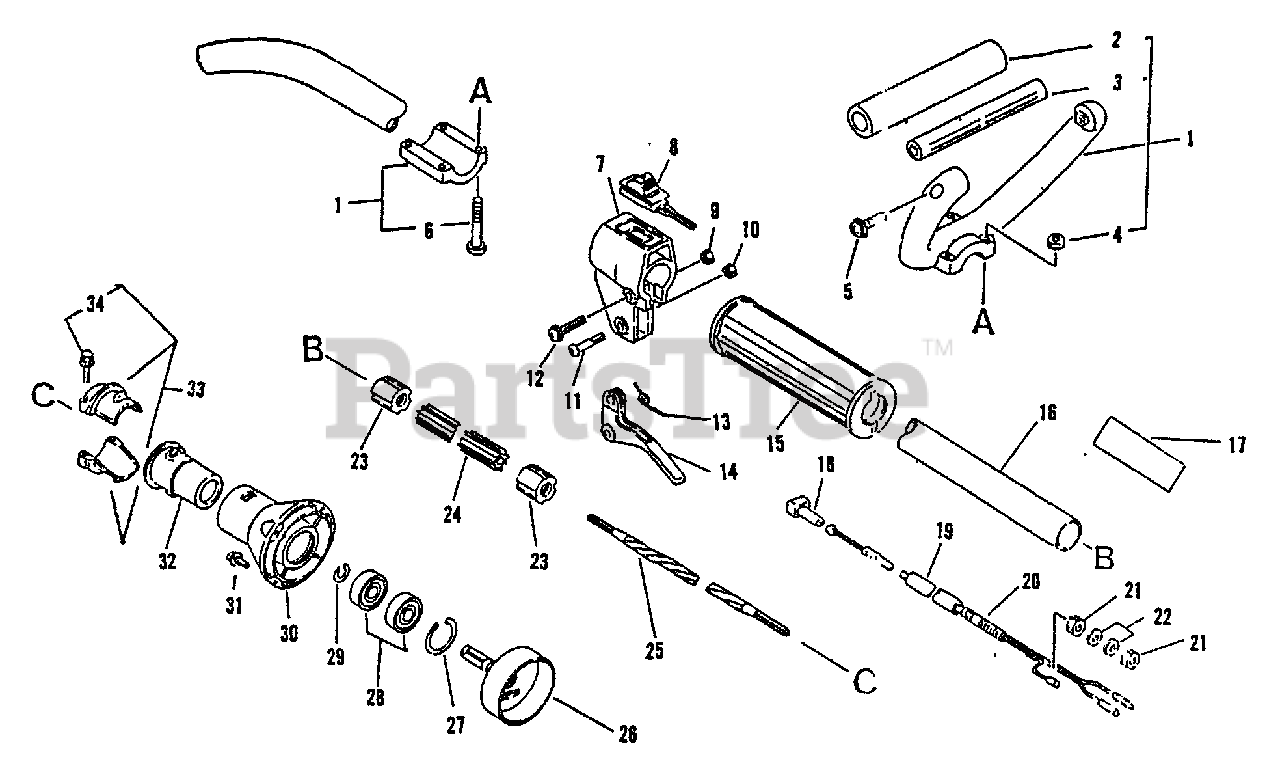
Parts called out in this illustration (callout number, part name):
1	LOOP HANDLE ASSY
2	GRIP, HANDLE
5	SCREW - 5X30
6	SCREW - 5X35
7	BRACKET, THROTTLE CONTROL
8	IGNITION SWITCH ASSY
10	LOCKNUT - 5
11	SCREW - 5X30
12	SCREW - 5X30
13	SPRING, TRIGGER
14	TRIGGER, THROTTLE
15	GRIP, HANDLE
16	MAIN PIPE ASSY
17	LABEL - CAUTION
18	GUIDE, CABLE
19	TUBE - VINYL
20	CABLE, THROTTLE
22	WASHER - 6
24	LINER - FLEXIBLE
25	DRIVESHAFT - FLEXIBLE
26	DRUM, CLUTCH
27	RING, RETAINING - 28
28	BEARING, BALL - 6001
29	RING, RETAINING - 12
30	CASE, CLUTCH - GRAY
31	SCREW - 5X16
33	HOLDER KIT
34	BOLT - 5X25
